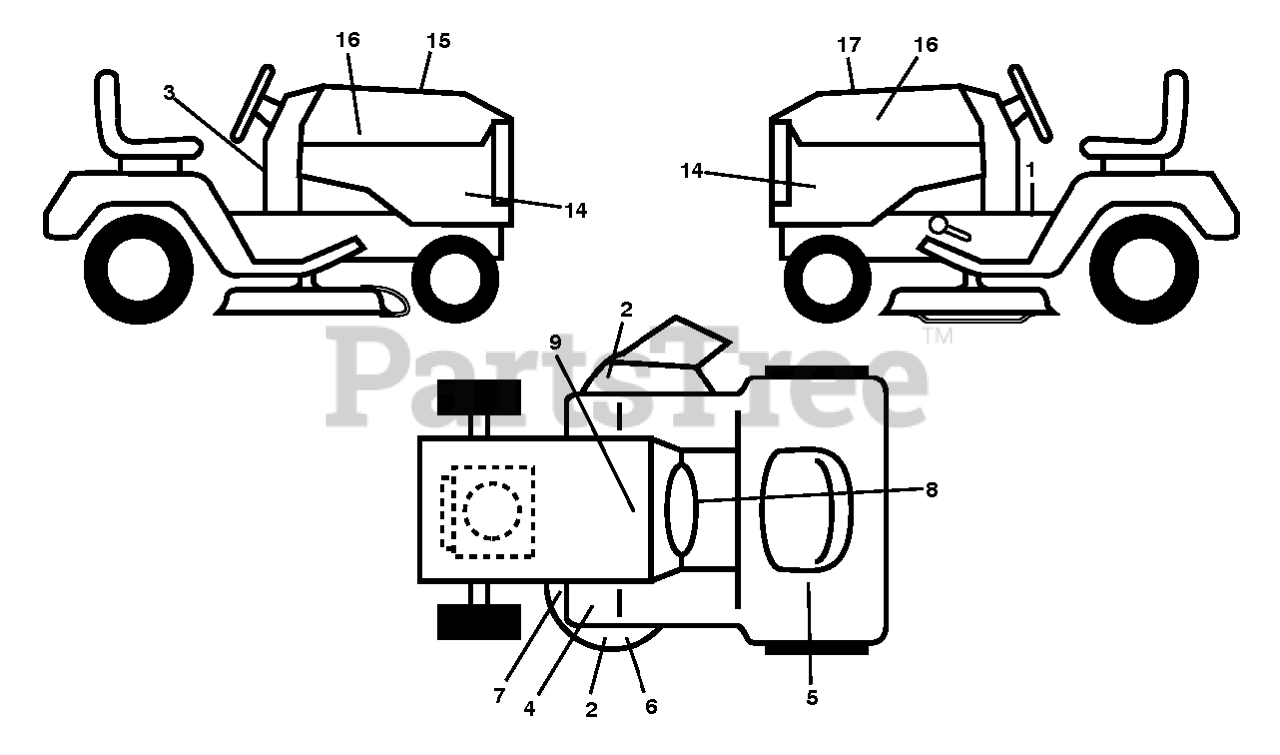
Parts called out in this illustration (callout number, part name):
1	DECAL.FENDER.WARNING
2	DECAL.DECK.6MIL.EURO.NOSTEP
3	LABEL.EMISS.CA.HUSQ/LOWES.2011
4	DECAL.PEDAL.HUSQ.CROWN
5	DECAL.WARN.RESERVE.FUEL
6	DECAL.DECK.6MIL./DEF.SHLD.WARN
7	DECAL.MOWER.SCH.48/54.PREM
8	DECAL, WARNING SPARK ARRESTOR
9	DECAL BTRY SYMBOLS
14	DECAL.SDPNL.HUSQGT2.GTH26V52LS
15	DECAL.WARNING.CUST.RESP.E85.
16	RP.DECAL.BADGE.170MM.TEXTLOGO
